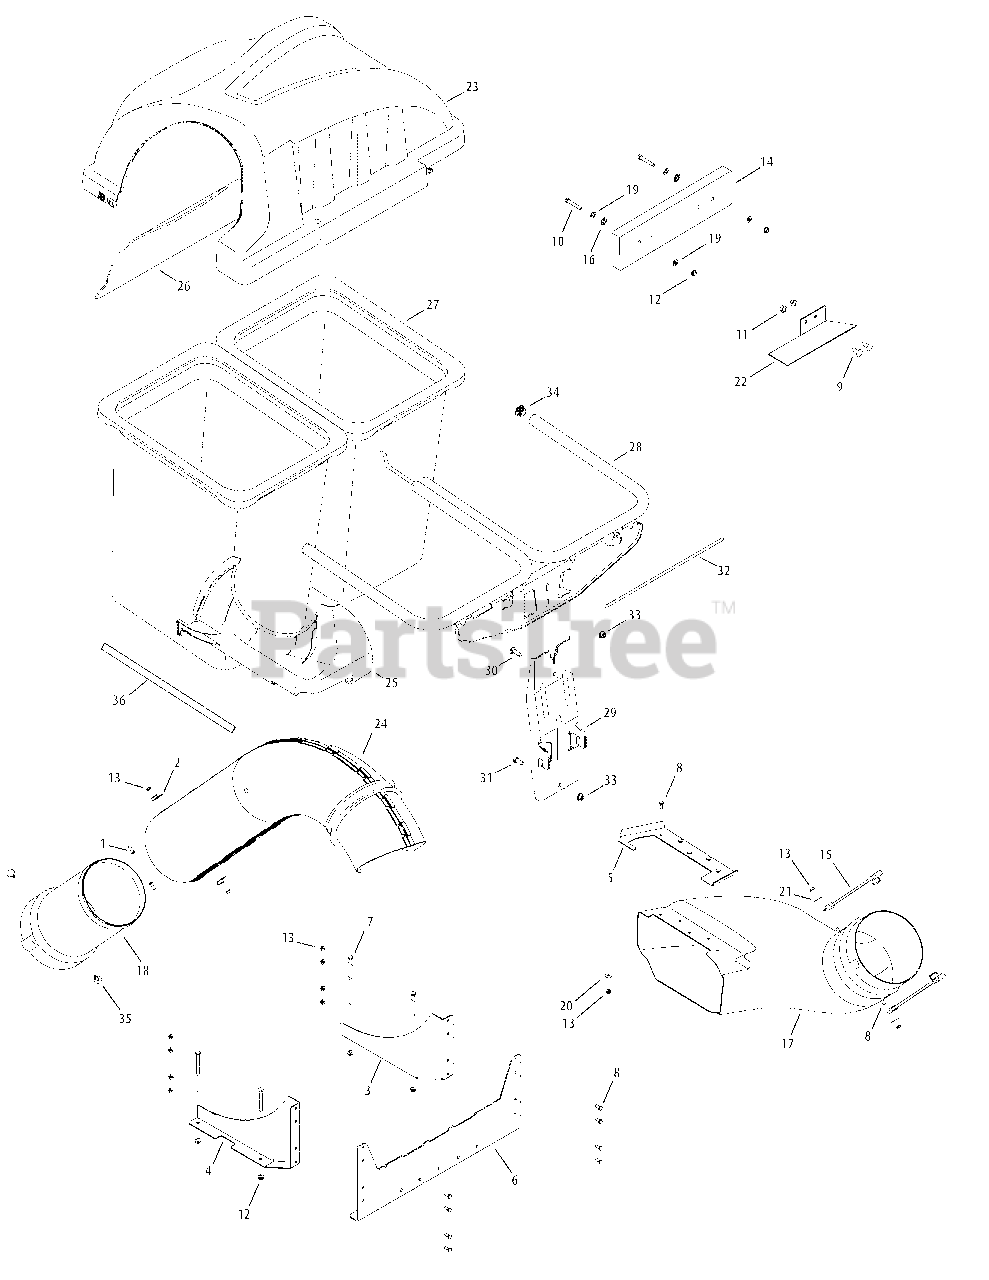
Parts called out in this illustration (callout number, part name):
1	Cap Screw, 1/4-20 x .750
2	Retainer Hook Bracket
3	Mount Assembly, RH
4	Mount Assembly, LH
5	Boot Mount Bracket
6	Catcher Mounting Bracket
7	Hex Head Screw, 5/16-18 x 2.75
8	Hex Head Screw, 1/4-20 x .620
9	Carriage Bolt, 3/8-16 x 1.00
10	Hex Head Screw, 5/16-18 x 2.00
11	Flange Lock Nut, 3/8-16
12	Flange Lock Nut, 5/16-18
13	Flange Lock Nut, 1/4-20
15	Chute Strap
16	Push Nut, 5/16
17	Discharge Chute Elbow
18	Chute Adapter
19	Flat Washer, .375 x .738 x .063
20	Belleville Washer
21	Flat Washer, .265 X 1.0 X .030
23	Twin Bagger Cover Assembly
24	Upper Chute Assembly
25	Upper Chute Support
26	Bagger Cover Screen
27	Grass-bag Assembly
28	Twin Bag Support Assembly
29	Vertical Support Bracket
30	Carriage Screw, 5/16-18 x 1.00"
31	Hex Head Screw, 5/16-18 x .75"
32	Cover Hinge Pin
33	Flange Lock Nut, 5/16-18
35	Ratchet Clip
36	Foam Strip
